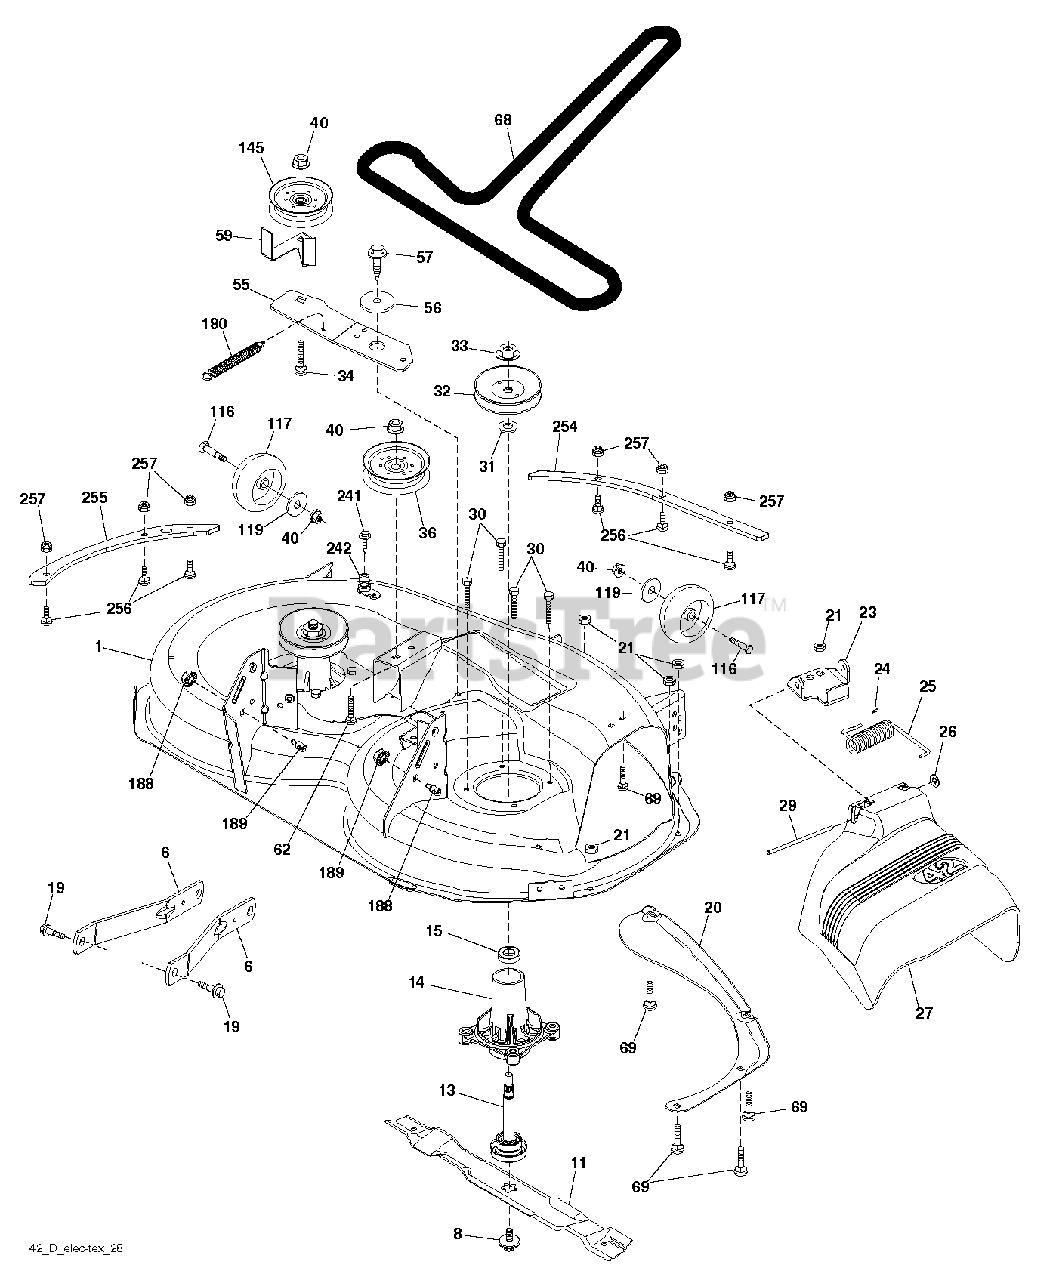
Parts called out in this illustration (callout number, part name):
1	DECK SVC 42"B 103 419175X498
6	ARM.SUSPENSION.MOWER.R
8	SCREW 7/16 X 20 X 1" HEX HEAD
11	42" HI-LIFT BLADE
13	RB MANDREL.ASM.SUB-NON.GR
14	HOUSING.MANDREL.REV.TALL.N/GRS
19	BOLT.SHOULDER
20	BAFFLE.VORTEX
21	LOCKNUT
23	BRKT.DEFLECTOR.38"2005+
24	CAP-SLEEVE LT
25	SPRING.TORSION.DEFLECT
26	NUT PUSH M
27	SHIELD.DEFLECTOR.MOWER.42"BLAC
29	ROD.HINGE
30	SCREW, WASHER HEAD
31	WASHER.SPACER.MANDREL
32	PULLEY/MANDREL
33	NUT.FLANGE.LOCK.TOP
34	BOLT.3/8-16X1.50
36	PULLEY.IDLER.2006
40	NUT LOCK FLG 3/8-16 UNC
55	IDLER.ARM.42"
56	SPACER.RETAINER
57	SCREW 3/8-16X1
59	GUARD, BELT
68	BELT V SECONDARY
69	BOLT
116	BOLT M
117	WHEEL.GAGE.HALF.SPOKED
119	WASHER
145	PULLEY.IDLER.48"PRIMARY
188	STUD.FASTNER.W/ANTI-ROTATE
189	NUT LOCK HEX FLANGE 5/16-18
190	SPRING.MOWER.DRIVE.ELECTRIC
241	SCREW.TT.#10-32X.5.3/8.FLANGE
242	RP MANDREL.ASM.REV.TALL.N/GRS
254	REINFORCEMENT.PLATE.42.FTX498
255	REINFORCEMENT PLATE 42 SD.X498
256	RHSNB, 1/4-20 X 1, GR5
257	NUT T
